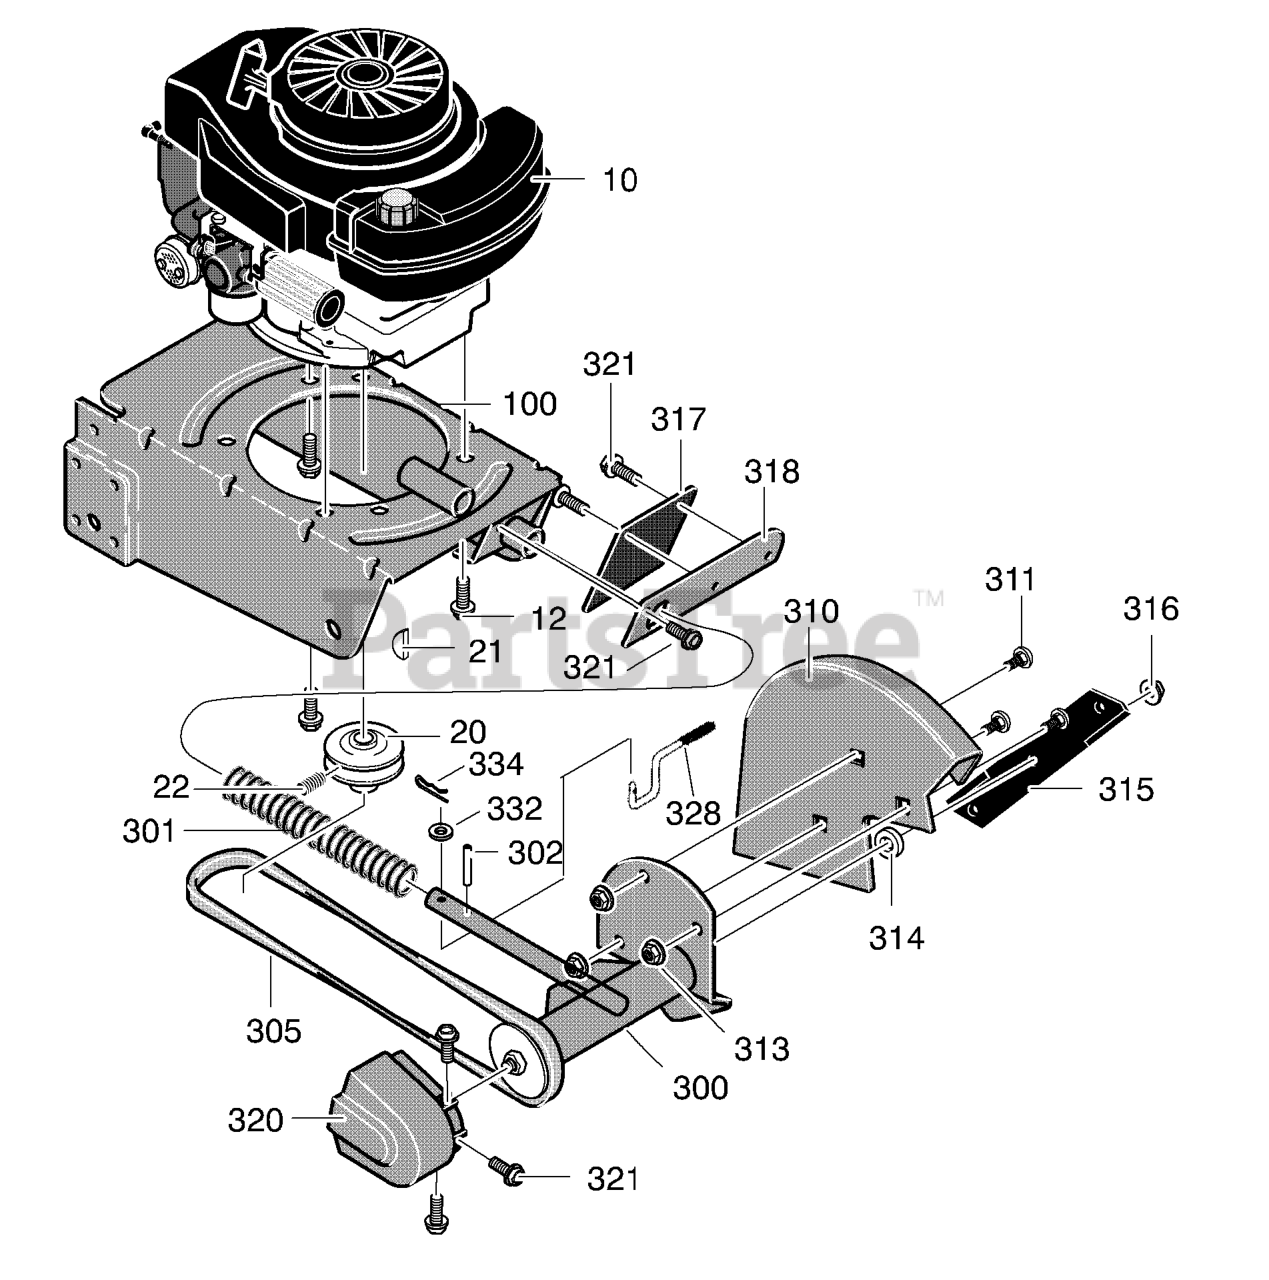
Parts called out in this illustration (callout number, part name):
10	Engine
20	Pulley, V3L
21	Key, Hi Pro #505
22	Screw, Set
100	Frame, Edger
300	Quill Assembly
302	Spring Pin
305	Belt, V4L
310	Blade Guard
311	Bolt, Carriage
313	Nut, 5/16-18
314	Flat washer
315	Blade, Edger
316	Nut, 1/2-20
317	Deflector, Rubber
318	Plate, Rubber Flap
320	Belt Guard
321	Screw, 10-16x.50
328	Lever, Blade
332	Washer
334	Pin, Hair
